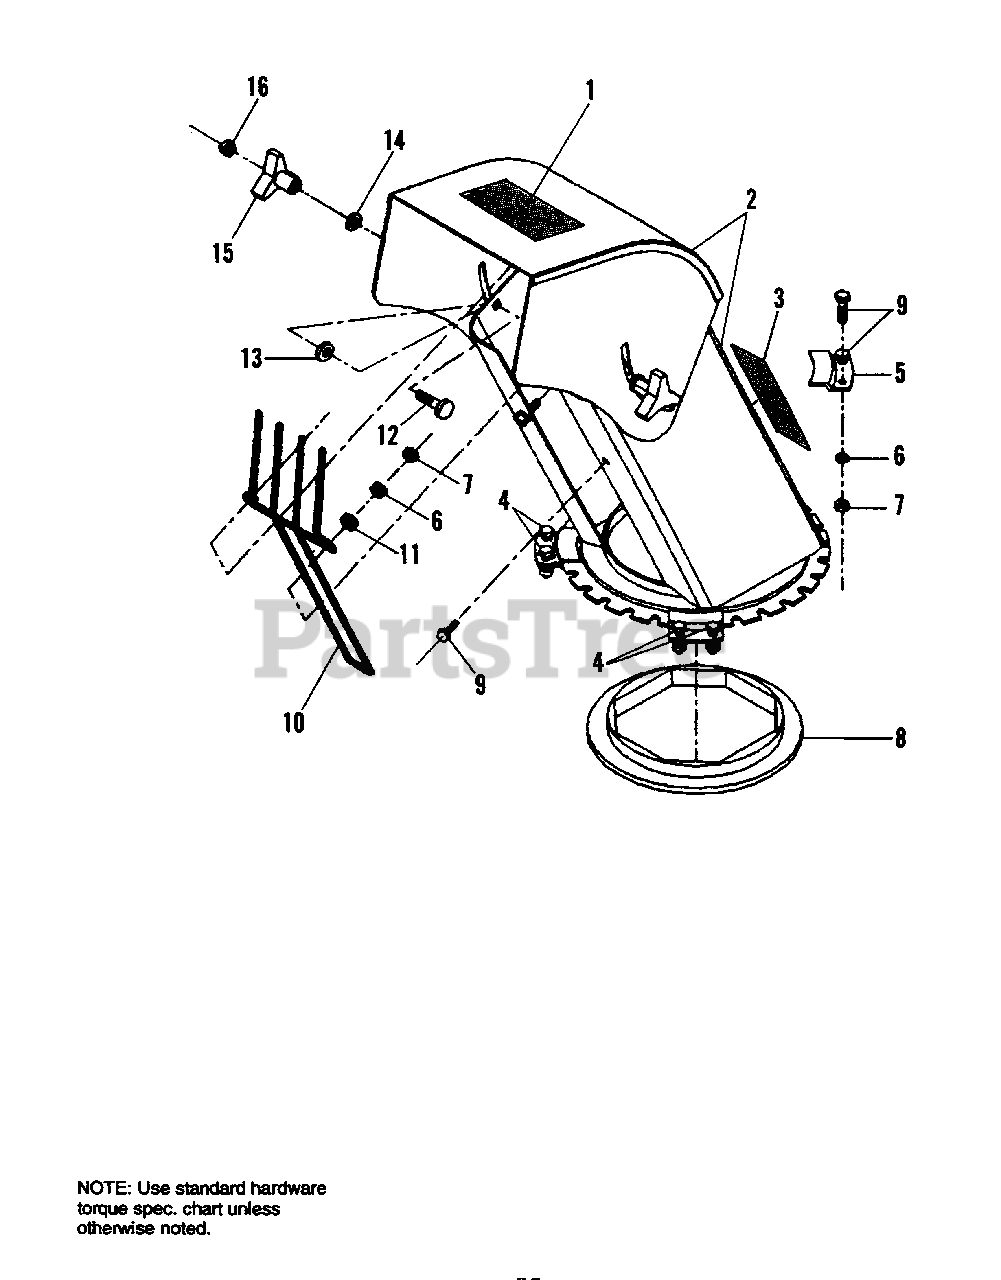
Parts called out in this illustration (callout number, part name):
1	DECAL, Danger
2	CHUTE & DEFLECTOR ASSY. w/Knobs & Decals
3	DECAL, Warning
4	CAPSCREW, Hex Hd., 1/4-20 x 1/2
5	PLATE, Retaining
6	LOCKWASHER, 1/4
7	NUT, Hex, 1/4-20
8	RING, Nylon
9	CAPSCREW, Hex Hd., 1/4-20 x 3/4
10	GUARD, Stone
11	WASHER, Plain, S.A.E. 5/16
12	BOLT, Carriage, 5/16-18 x 1-1/4
13	WASHER, Plain, S.A.E. 7/16
14	WASHER, Plain, S.A.E. 3/8
16	NUT, Hex Centerlock, 5/16-18
